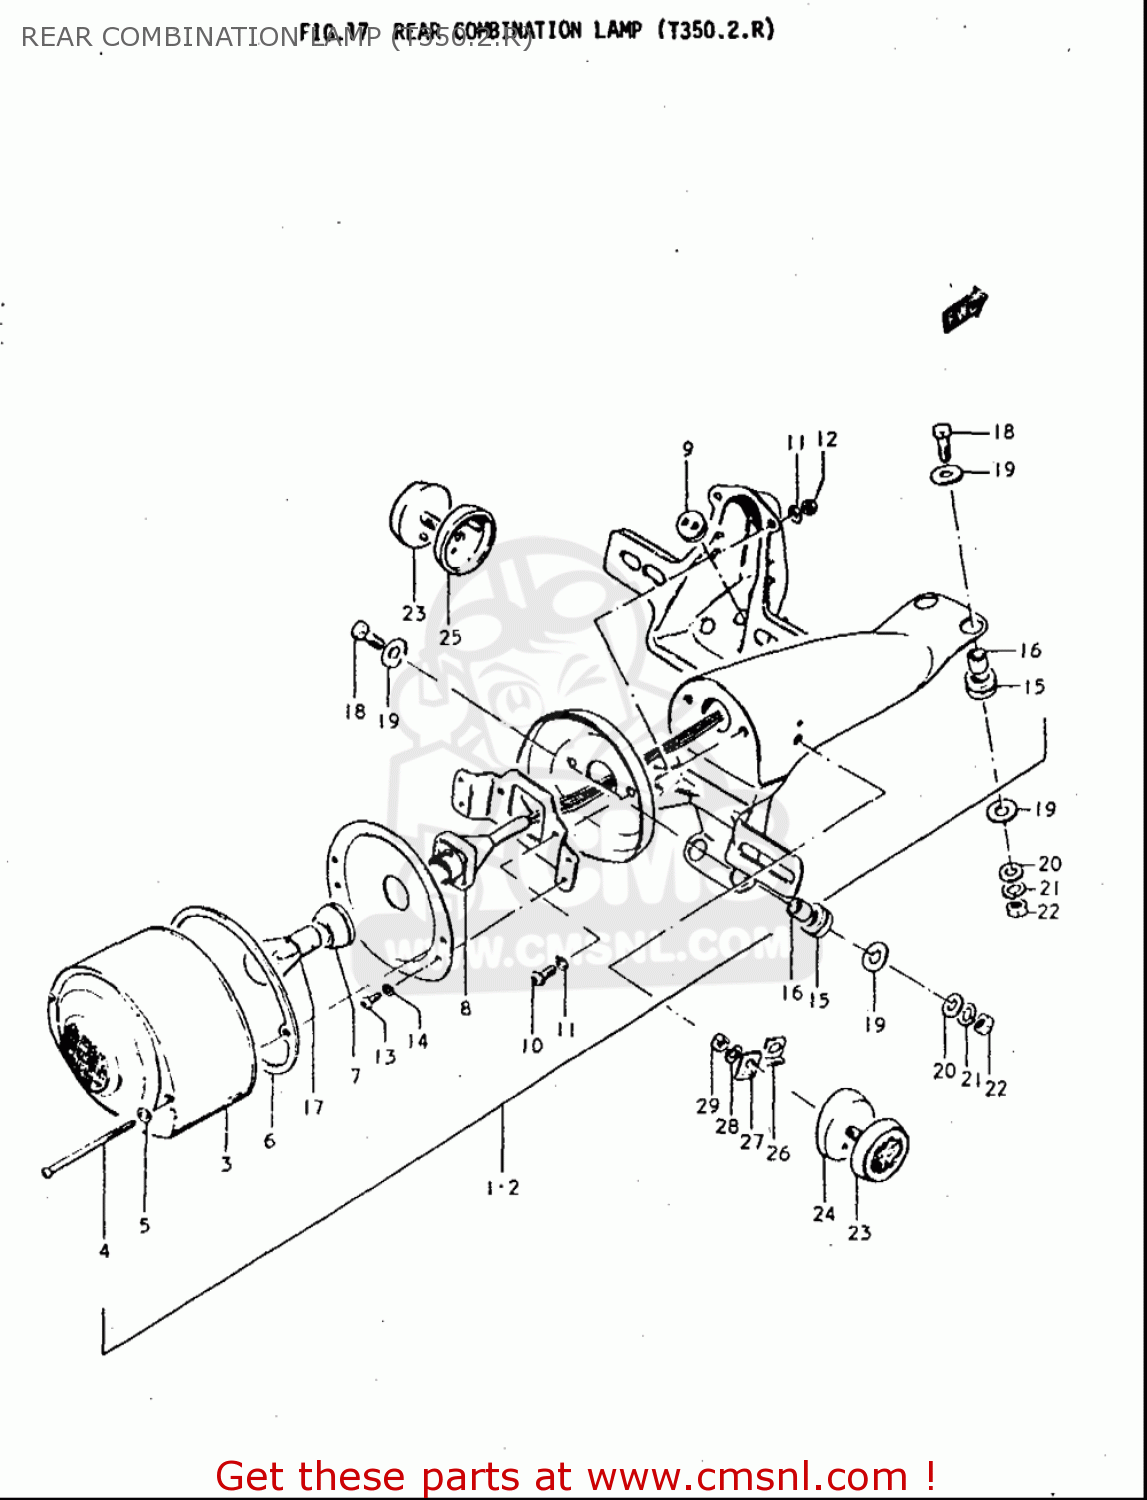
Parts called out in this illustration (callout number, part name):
3	LENS,RR COMBINATION LAMP
9	GROMMET,REAR COMBINATION LAMP
11	WASHER,LOCK
12	NUT
14	WASHER,LOCK
15	CUSHION
16	SPACER
17	BULB(12V23W)
18	BOLT
19	WASHER(6.5X20X1.6)
20	WASHER
21	WASHER,LOCK
22	NUT
28	WASHER,LOCK
29	NUT
